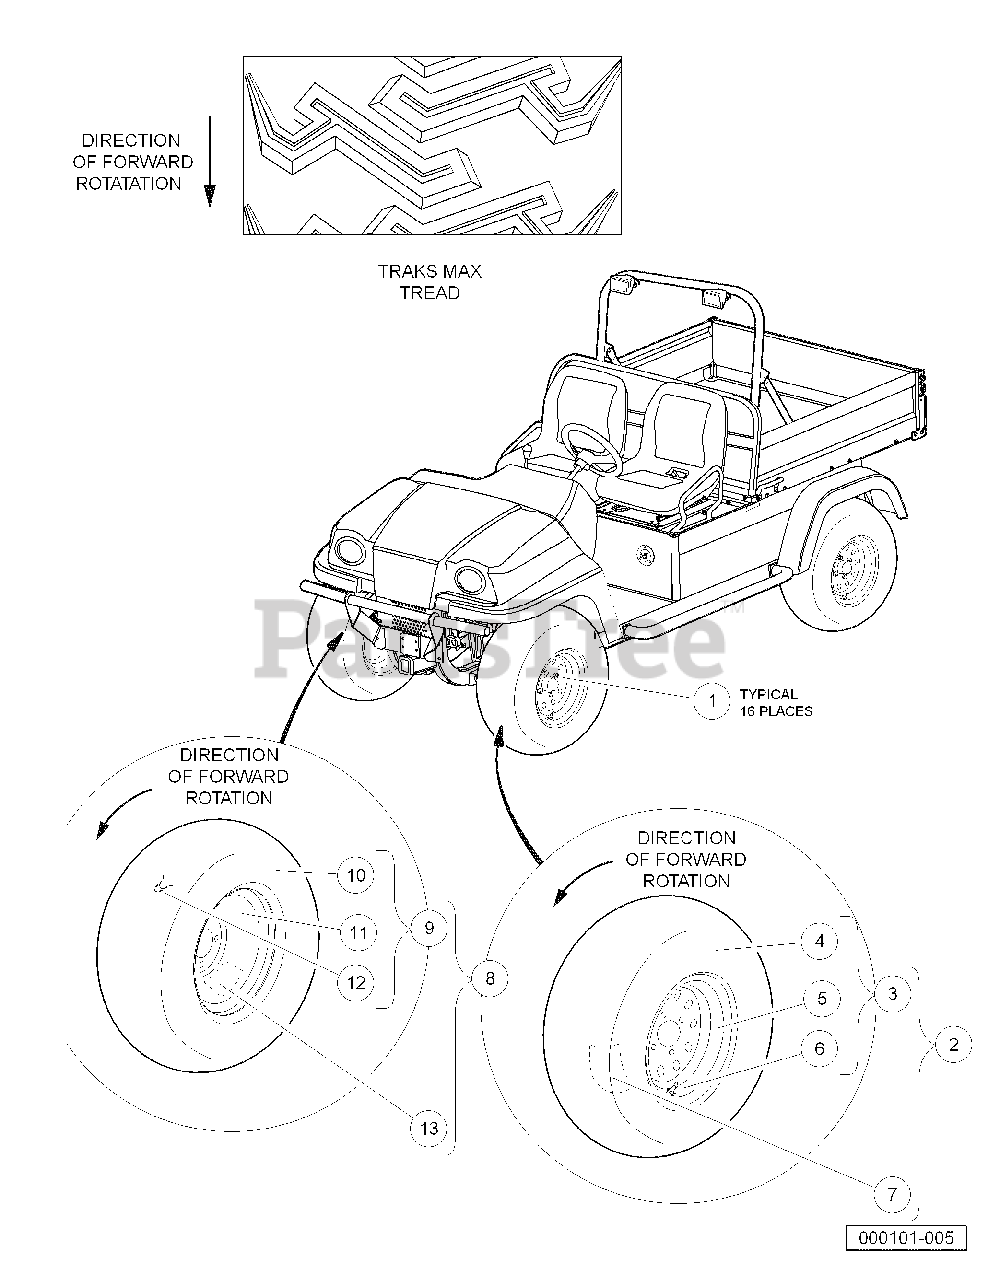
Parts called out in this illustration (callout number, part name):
1	.500-20 Unf Lug Nut
2	Tire Asm, Traks Max L Service
3	Gray Tire Asm Traks Max II L
4	Tire, Traks Max II L
5	Wheel Rim 10" Gray
6	Valve Stem
7	Decal, Brake Warning
8	Tire Asm, Traks Max R Service
9	Gray Tire Asm Traks Max II R
10	Tire, Traks Max II L
11	Wheel Rim 10" Gray
12	Valve Stem
13	Decal, Brake Warning
